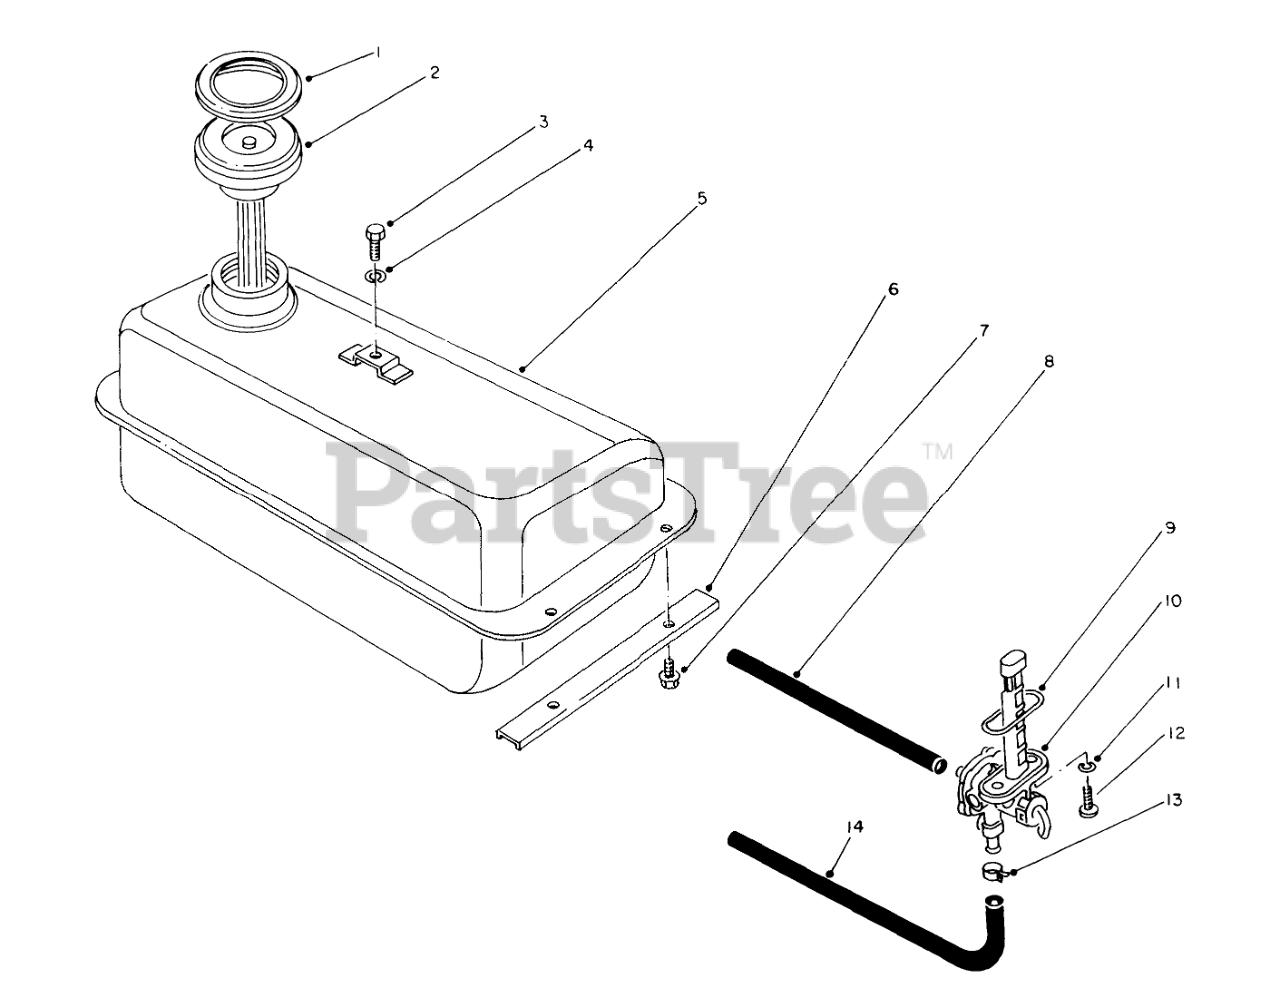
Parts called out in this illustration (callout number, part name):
1	Grommet
2	Gas Cap Assembly
4	Washer
5	FUEL TANK ASY
6	Clamp-Fuel Tank
9	0-Ring
10	Cock Assembly (Incl. Ref. #9)
11	GASKET (6.2X11X1)
12	Screw
